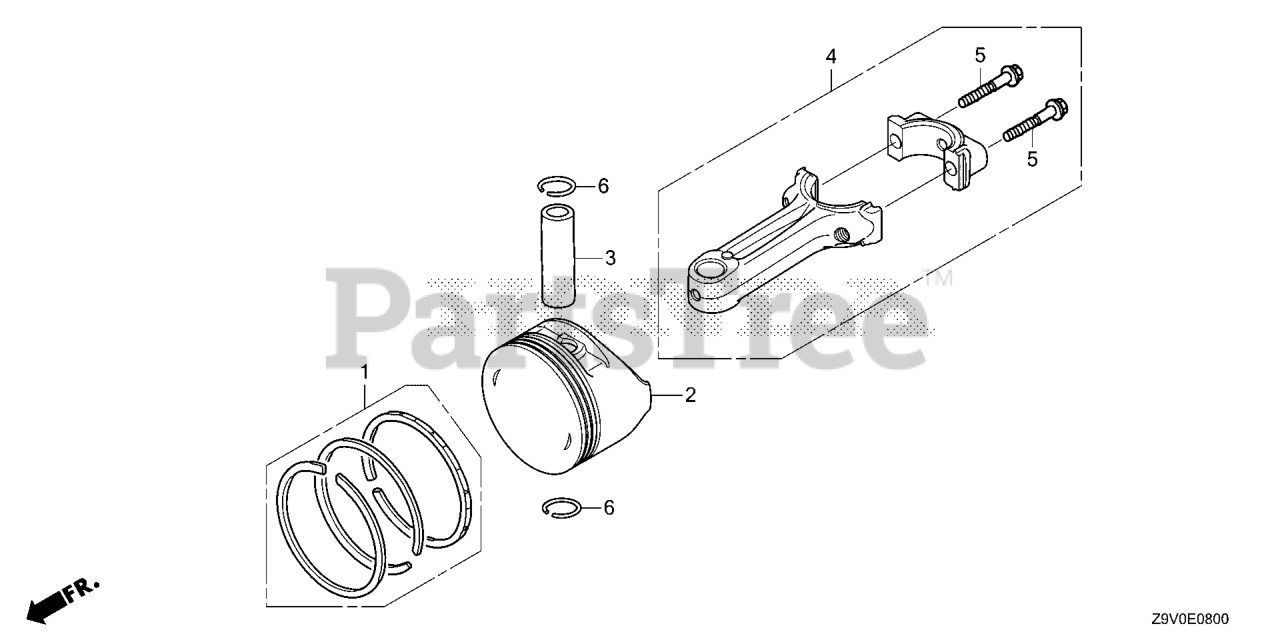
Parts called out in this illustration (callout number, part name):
1	RING SET, PISTON
3	PIN, PISTON
4	ROD ASSY., CONNECTING
5	BOLT, CONNECTING ROD
6	CLIP, PISTON PIN (13MM)
